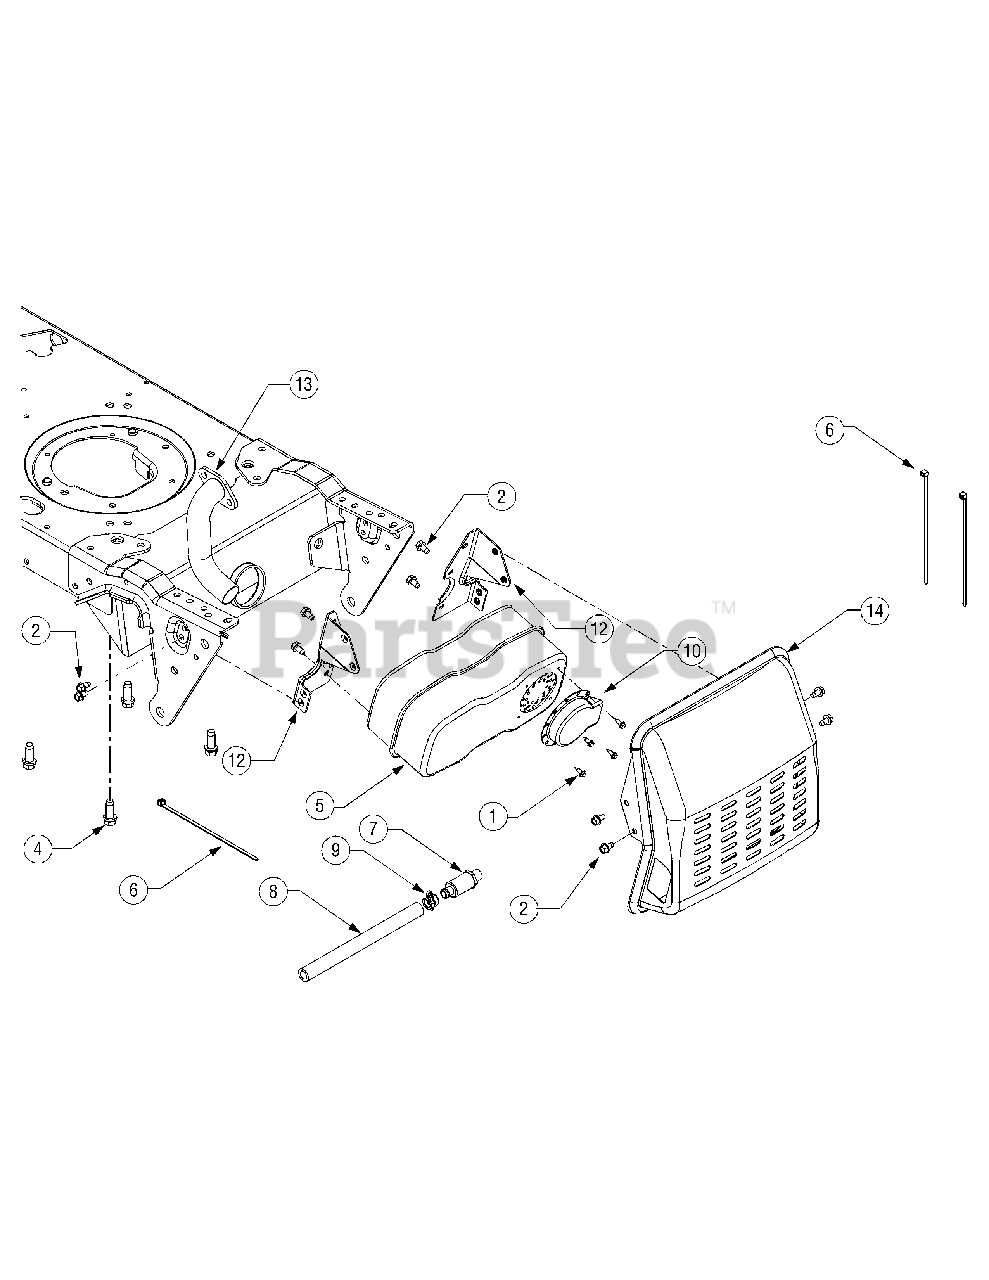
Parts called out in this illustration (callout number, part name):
1	Screw, #8-18, 0.500
2	Screw, Hex, 1/4-20, 0.500
3	Screw, Hex, 5/16-12 x .75
4	Screw, Hex, 3/8-16 x 1.00
5	Muffler, Single Inlet
6	Cable, Tie, 3/16 x .05 x 7.4
8	Extension Hose, Oil Drain
9	Cap, Oil Drain
10	Deflector, Muffler
11	Muffler Bracket, LH
12	Muffler Bracket, RH
13	Pipe, Exhaust
14	Shield, Muffler
